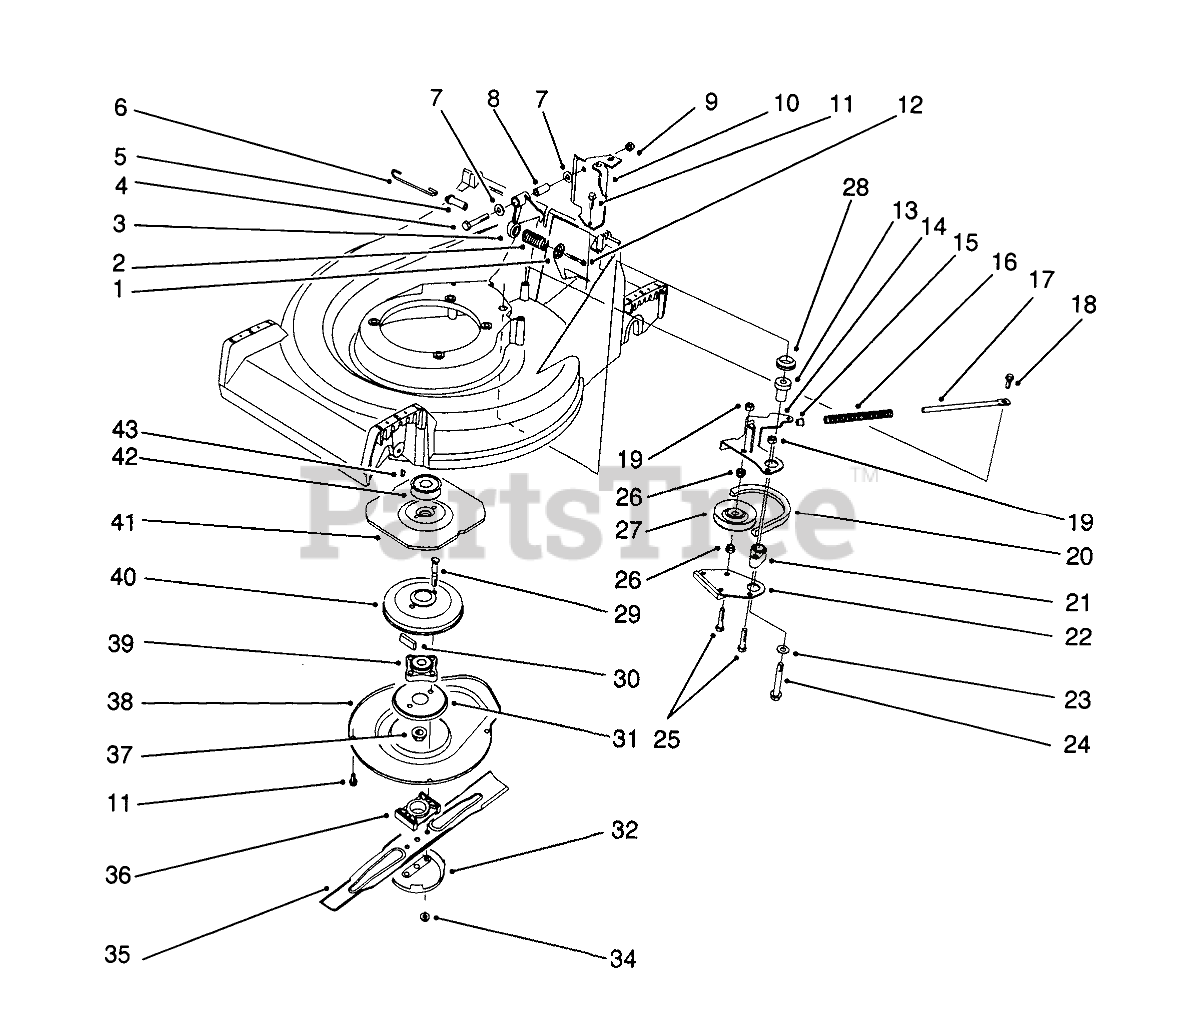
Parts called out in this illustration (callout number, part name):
1	RETAINER-SPRING
2	COMPRESSION SPRING
3	CRANK
4	SCREW-HH
5	SPRING PIN
6	CONTROL LINK
7	WASHER-PLAIN
8	STRAIGHT BUSHING
10	Bracket-Cable Support
11	SCREW-HWHTF
12	SCREW-HWHTF
13	BBC PM BUSHING
14	Lever
15	SPACER
16	COMPRESSION SPRING
17	SPRING ROD
18	SCREW-SHOULDER
19	NUT-LOCK, NI
20	V-BELT
21	BRAKE PLATE HUB
22	BRAKE SHOE
23	WASHER-PLAIN
24	3/8-16 X 2-3/4 CAPSCR
25	SCREW-HH
26	IDLER PULLEY HUB
27	PULLEY-IDLER
28	V-RING SEAL
29	BOLT-BLADE
30	DAMPENER-VIBRATION
31	Screen-BBC
32	CUP-SCALP, ANTI
34	NUT-LOCK
35	Key
36	SPACER-BLADE
37	NUT-LOCK, NI
38	Cover
39	HUB ASM
40	BRAKE DRUM
41	FLYWHEEL - BBC
42	PULLEY
43	KEY-WOODRUFF
